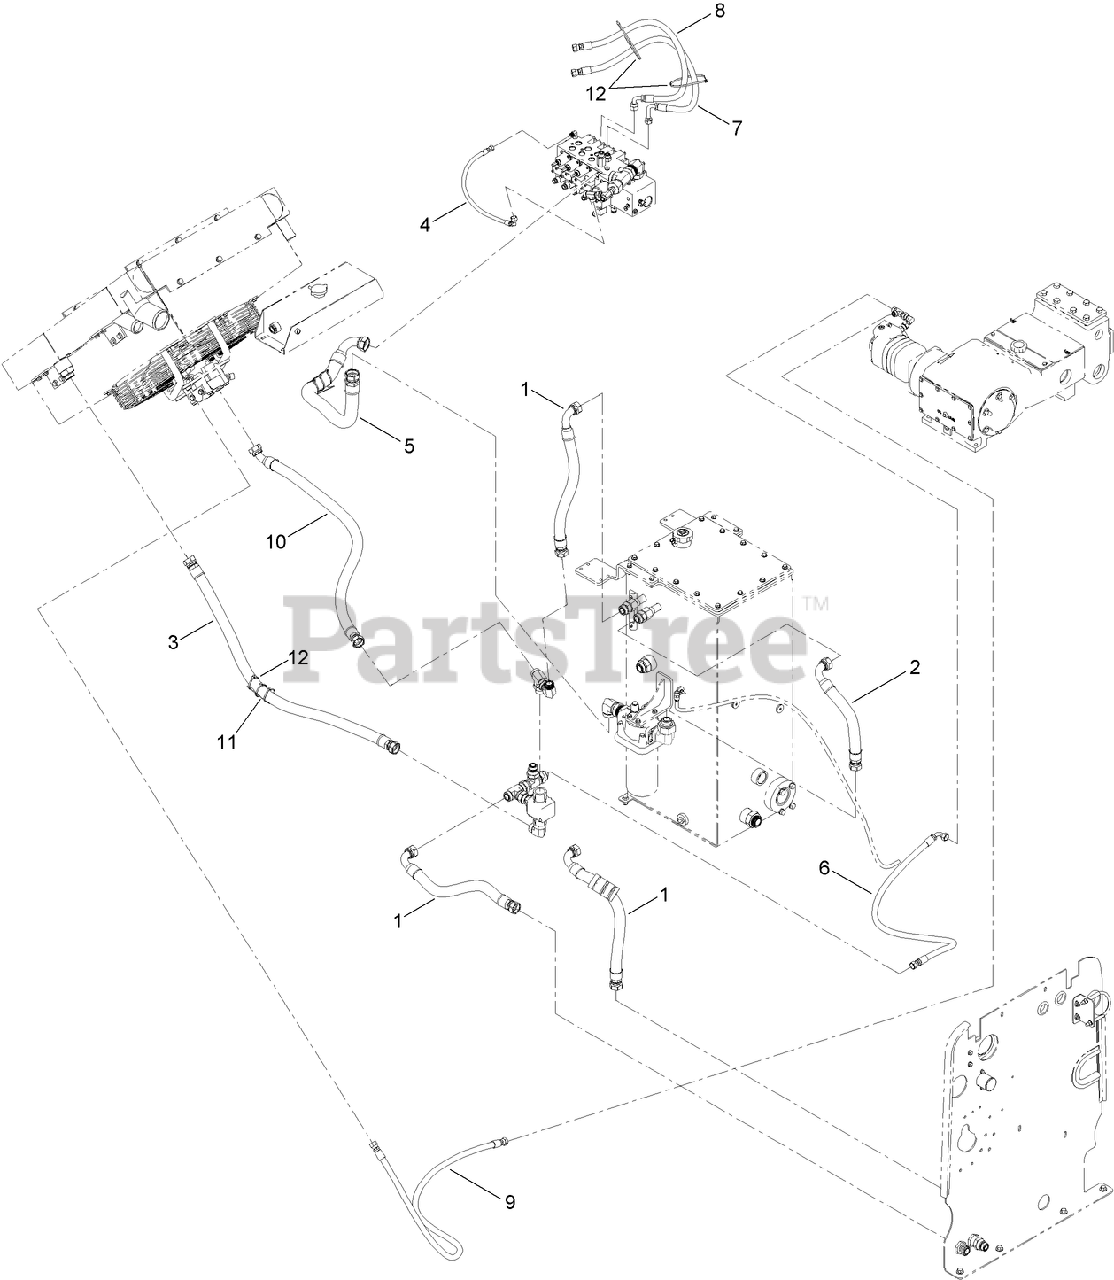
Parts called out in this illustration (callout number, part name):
1	HOSE ASM-HYD
2	HOSE ASM-HYD
3	HOSE ASM-HYD
4	HOSE ASM-HYD
5	HOSE ASM-HYD
6	HOSE ASM-HYD
7	HOSE ASM-HYD
8	HOSE ASM-HYD
9	HOSE ASM-HYD
10	HOSE ASM-HYD
11	PROTECTOR-HOSE
12	TIE-CABLE
